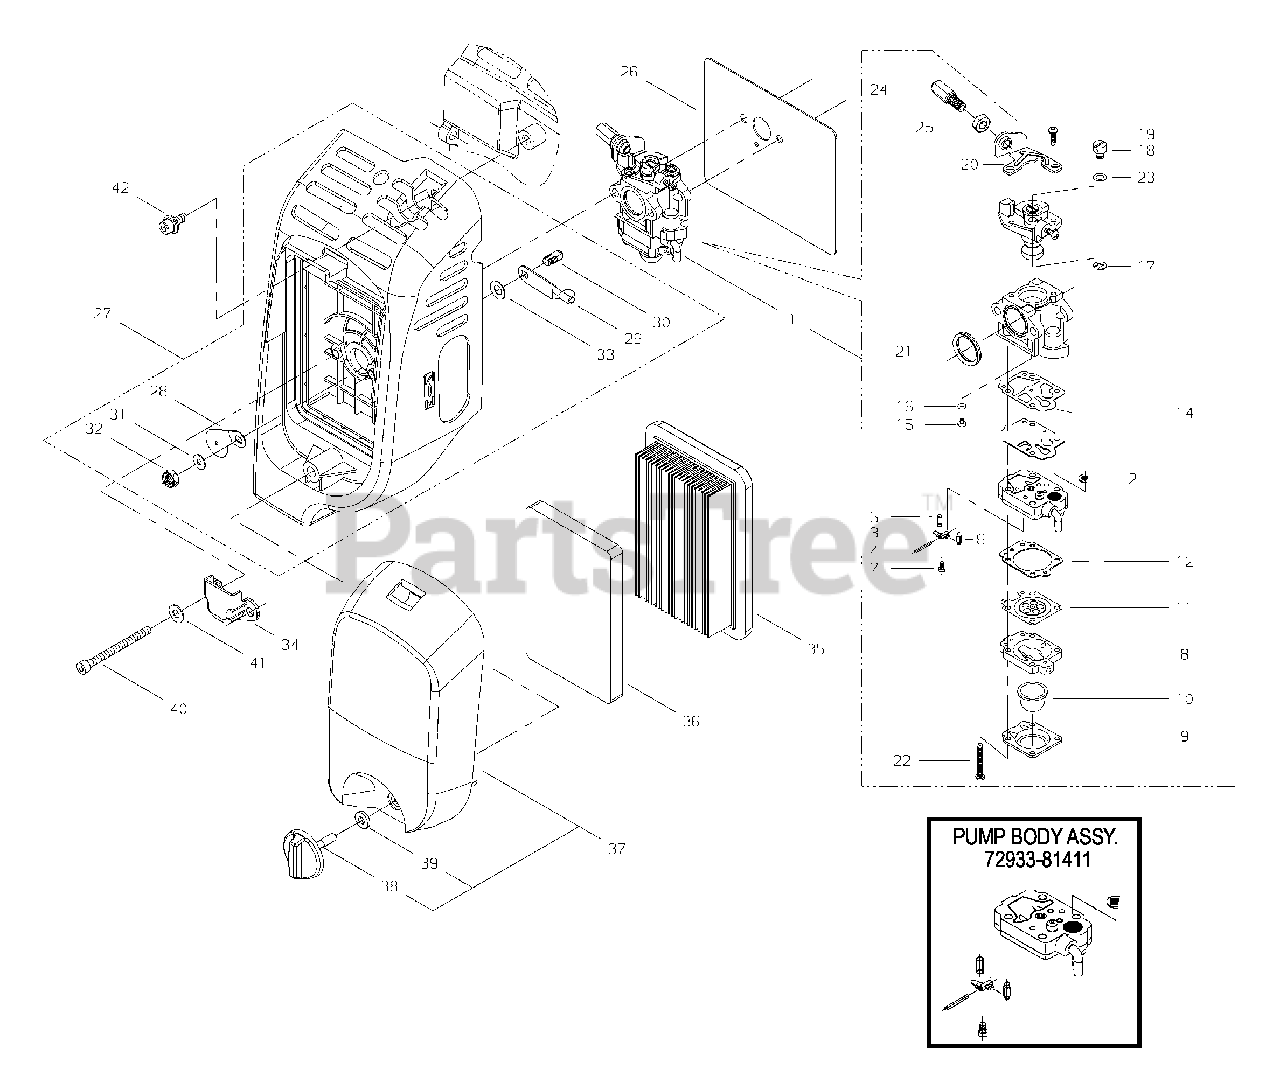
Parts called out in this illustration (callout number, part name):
1	CARBURETOR
2	STRAINER
3	LEVER, METERING
4	PIN, METERING LEVER
5	SPRING, METERING LEVER
6	VALVE, INLET NEEDLE
7	SCREW, METERING LEVER PIN
8	BASE, PURGE
9	RETAINER, PURGE BULB
10	BULB, PURGE
11	DIAPHRAGM, METERING
12	GASKET, METERING
13	DIAPHRAGM, PUMP
14	GASKET, PUMP
15	JET, MAIN
16	O-RING
17	RING, RETAINING
18	SWIVEL
19	SCREW
20	BRACKET, CABLE
21	SEAL
22	SCREW, PUMP COVER
23	WASHER
24	NUT, CABLE ADJUST
25	NUT
26	GASKET
27	AIR FILTER CASE ASSY
28	PLATE, CHOKE
29	LEVER, CHOKE
30	SHAFT, CHOKE
31	LOCKWASHER - 6
32	NUT - 6
33	WASHER - CONICAL
34	DEFLECTOR PLATE
35	FILTER, AIR
36	PRE-FILTER
37	AIR FILTER COVER ASSY
38	THUMBSCREW
39	WASHER - VINYL
40	SCREW - 5X65
41	WASHER - 5
42	SCREW - 5X14
